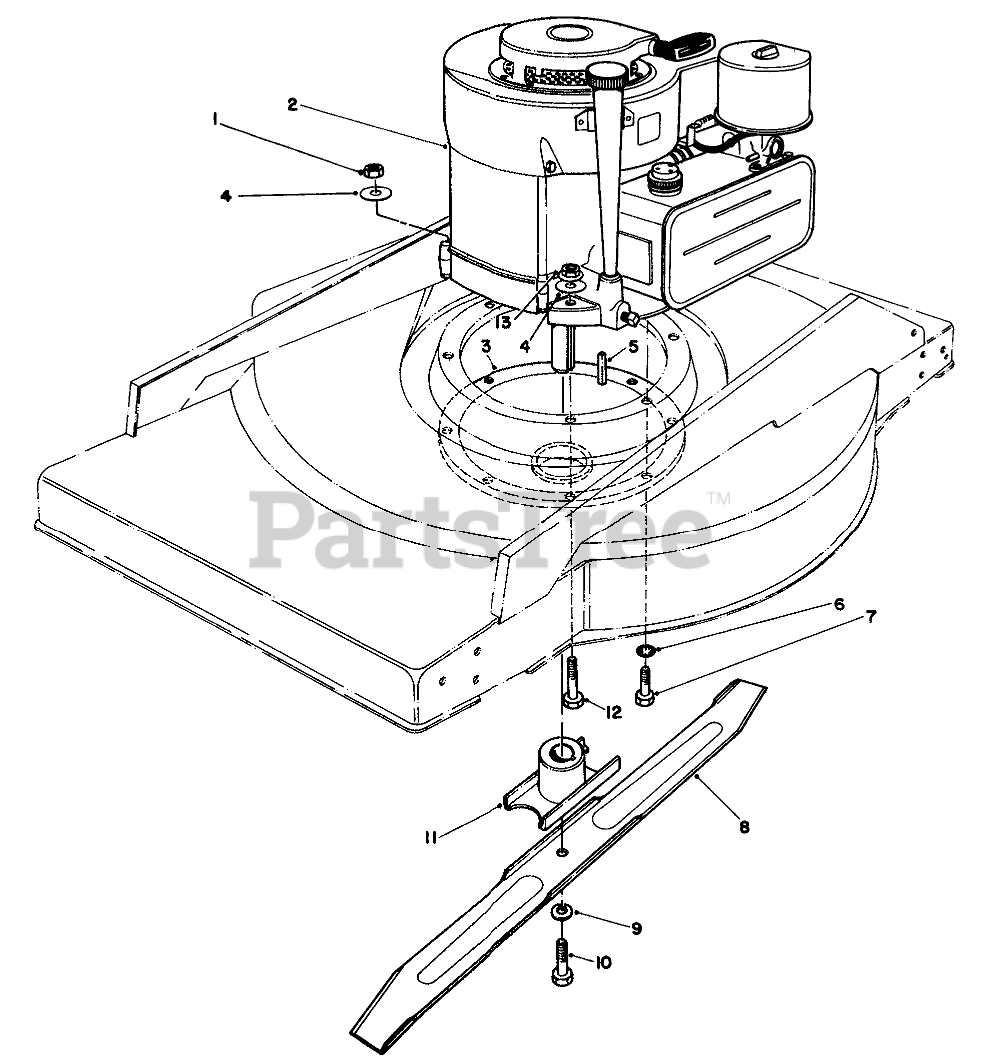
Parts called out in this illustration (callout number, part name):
1	NUT-LOCK, CONE
3	PROTECTOR-CRANKSHAFT
4	WASHER-FLAT
5	Key-Square
6	WASHER-LOCK, INTERNAL
7	SCREW-HWHTF
8	Blade
9	WASHER-LOCK
10	SPECIAL SCREW
11	BLADE RETAINER W A
12	SCREW-HH
13	NUT-HF
